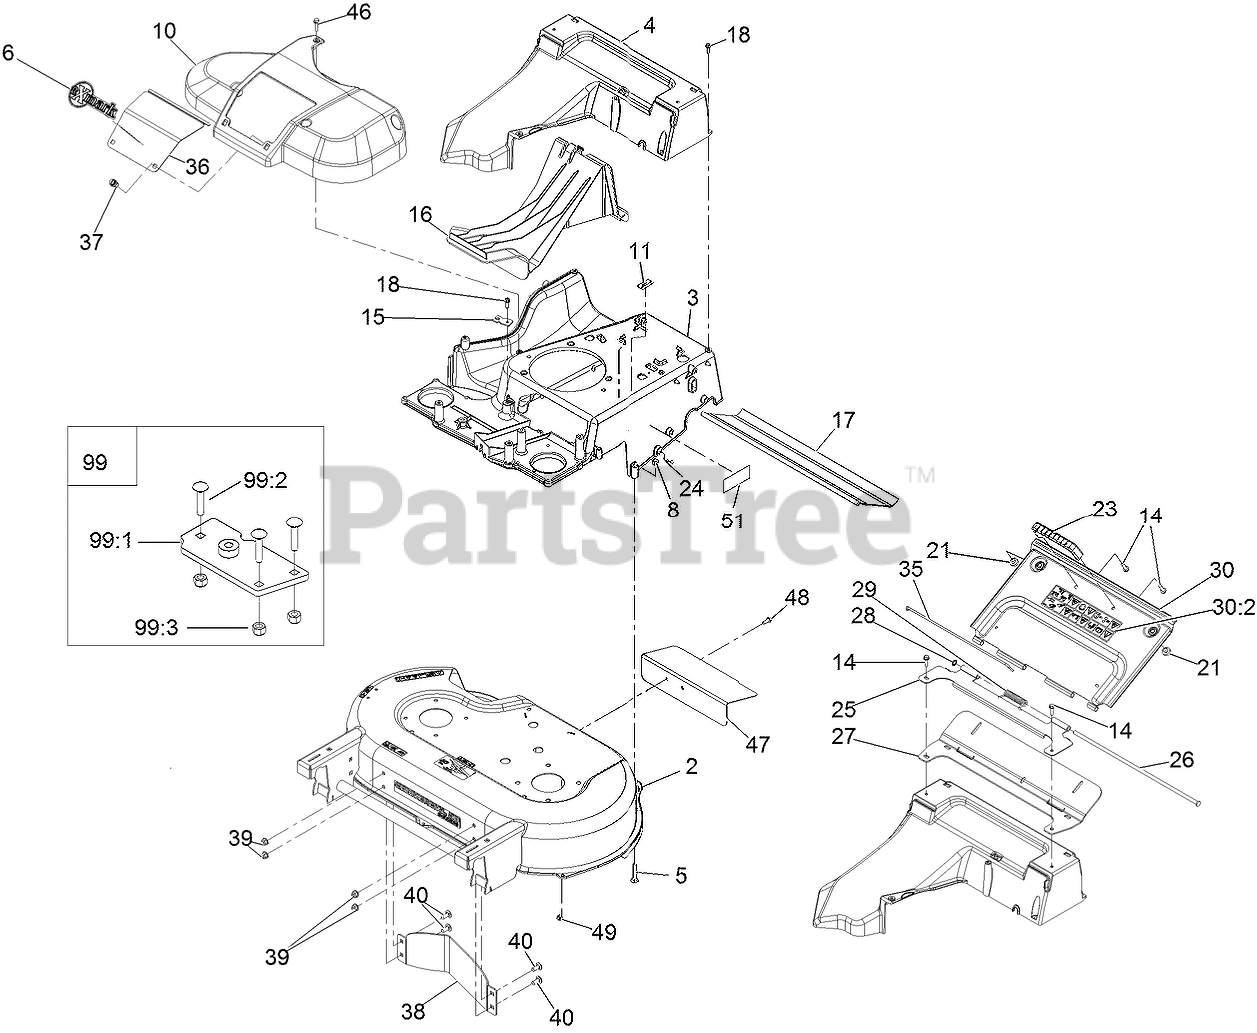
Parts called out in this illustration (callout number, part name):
2	DECK-30, W/DECALS
3	FRAME
5	BOLT-CAR
6	DECAL-EXMARK LOGO
8	NUT-LOCK, NI
10	COVER-BELT
11	Decal-Patent Ttco.Com
14	SCREW-HWH
15	BRACKET-CABLE, TRACTION
16	PLUG-MULCH
17	SHIELD-TRAILING
18	SCREW-HWHTF
23	HANDLE-DOOR
24	SCREW-PTH
25	BRACKET-HINGE
26	PIN-HINGE
27	SEAL-DOOR
28	RING-RETAINING
29	SPRING-TORSION, COVER
30	REAR DOOR ASM
30:2	DECAL-WARNING
35	CLIP-SEAL
36	DOOR-ACCESS
37	FASTENER
38	BAFFLE-CONTROL
39	NUT-HF, NI
40	SCREW-HSBH
46	SCREW-HWHTF
47	DEFLECTOR-REAR
48	SCREW-HWH
49	NUT-LOCK, NI
51	DECAL-ARRESTOR, SPARK
99	FRAME PLATE KIT
